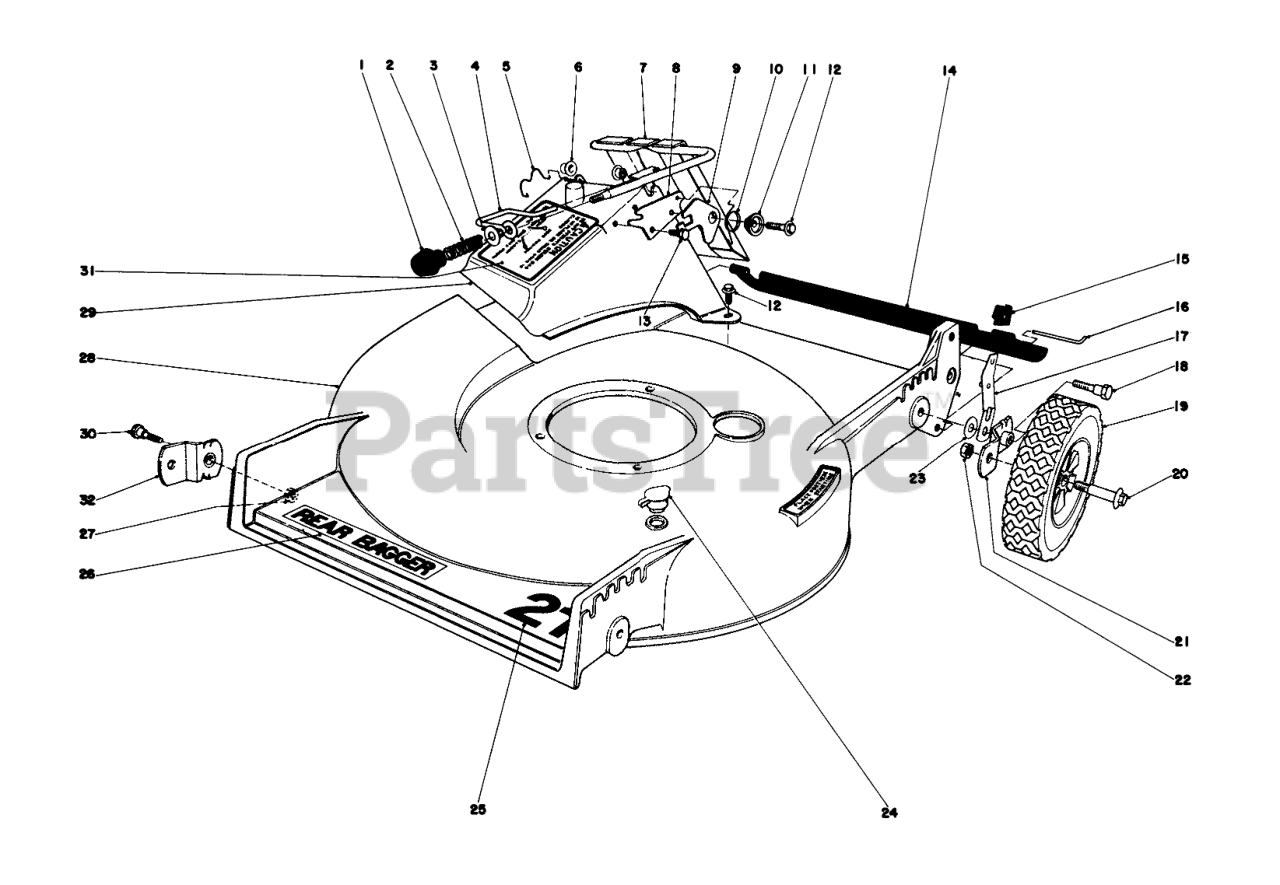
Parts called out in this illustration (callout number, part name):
2	COMPRESSION SPRING
3	WASHER
4	DOOR LATCH
5	DOOR RETAINER
6	BUSHING-NYLON
7	DOOR & HANDLE WA
8	DOOR LATCH PLATE
9	Latch Safety
10	TORSION SPRING
11	Latch Spacer
12	Screw
13	SCREW-HWH
14	SHIELD - TRAILING
15	KNOB-ARM
16	Rod Shield
17	SPRING ARM ASM (R&S)
18	5/16-18 PIVOT SCREW
19	WHEEL TIRE ASM 8 IN
20	BOLT-WHEEL
21	PIVOT ARM ASM A
22	Nut
23	WASHER-PIVOT
24	WASHOUT PLUG
25	Decal 21"
26	DECK DECAL
27	Nut
28	Deck
29	DISCHARGE CHUTE B
30	PIVOT SCREW
31	Decal Caution
32	PIVOT ARM ASM B
